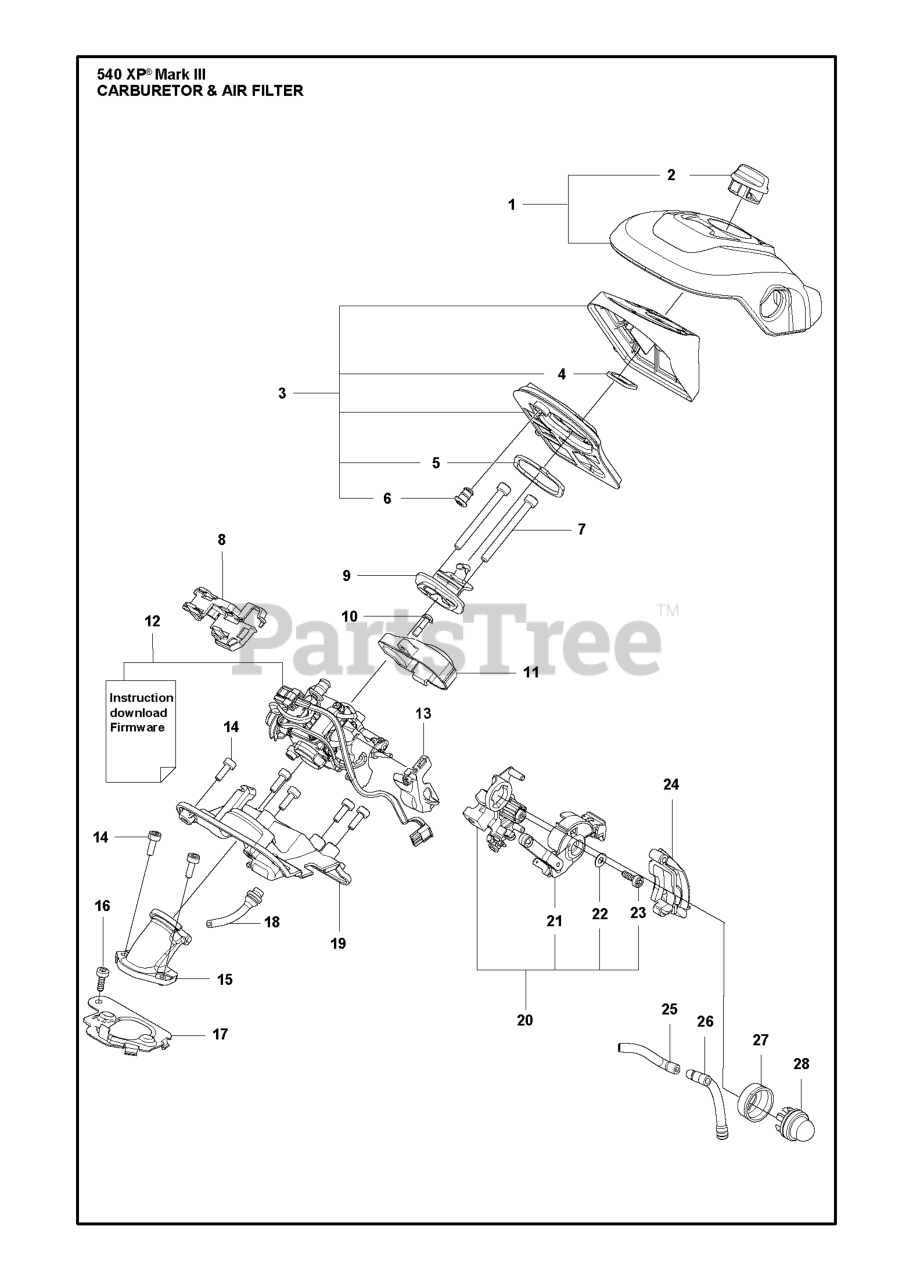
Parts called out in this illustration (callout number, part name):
14	BOLT M4 X 12 T27
16	SCREW
23	SCREW
28	PRIMARY BTN
